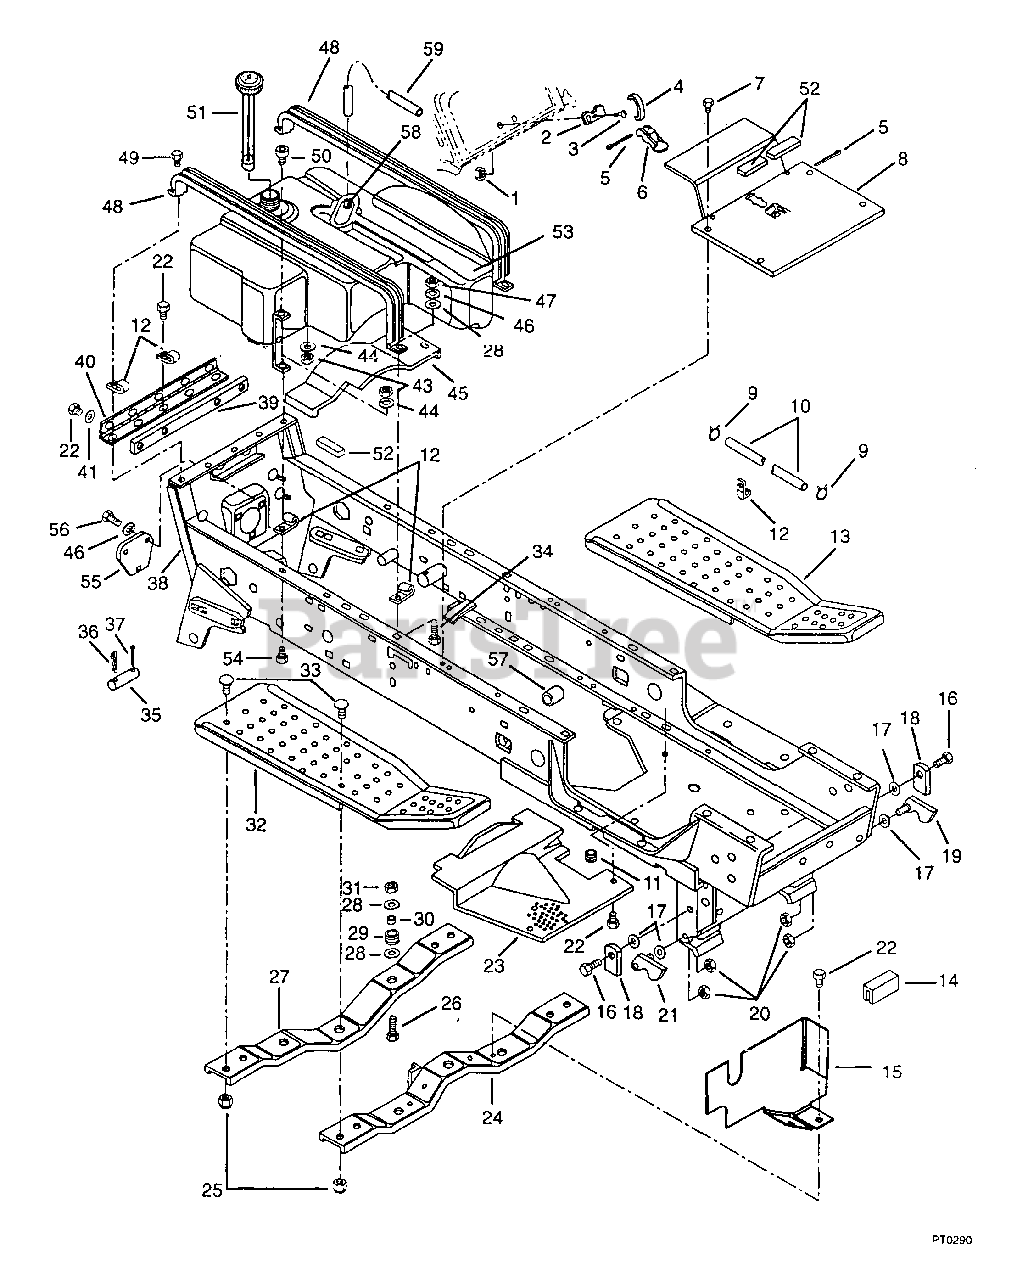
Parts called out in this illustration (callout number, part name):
1	NUT-LK DUAL FACE 10-24 PL
3	SCR-MCH 10-24X.50 SLRH PL
4	SPRING - DECK LATCH
5	PIN-COTR .12 X 1.25 PL
6	LEVER - DECK LATCH
7	SCR-TAP .250-20X.37 HWH PL TR
8	PLATE - FLOOR
9	CLAMP-HOSE WIR.490/.510X.092#8
10	FUEL LINE 1/4 X 67"
11	HOLE PLUG 1.375
12	J-CLAMP
13	L.H. RUNNING BOARD
16	BLT-HEX .38-16X1.00 PL
17	SPRING WASHER
18	LOCK STOP
19	LATCH LH
20	NUT-LK TOP .375-16 GR C YWZC
21	LATCH RH
22	SCR-TAP .312-18X.50 HWH PL TR
24	FRONT CHANNEL
25	NUT-FLG. .312-18 PL
26	BLT-HEX .31-18X1.25 PL GR2
27	REAR CHANNEL
28	WSHR-FL-STL .38X.875X.083 PL
29	GROMMET .438ID X .688 OD
30	SPACER .318X.430X.375
31	NUT-LK .312-18 GR A PL
32	R.H. RUNNING BOARD
33	BLT-RDHDSQSHNK .31-18X.50 YZ
34	BLT-RDHDSQNK .31-18X.75 SHT PL
36	PIN-HAIR INT .14X.4X2.75
37	PIN-COTR .12X1.0 PL
38	MAIN FRAME
40	HINGE-2" X 12.88 YWZC
41	WSHR-FL-STL .38X.875X.083 PL
42	SUPPORT
43	NUT-HEX .250-20 PL
44	WSHR-LK .250X.077 HVY PL
46	WSHR-LK .312X.097 PL HVY
47	NUT-HEX .312-18
48	CHANNEL
49	SCR-TAP .312-18X.75 HWH PL TR
50	SCR-SKH .25-20X.75 TSPH PL
51	GAS GAUGE & CAP
52	FOAM TAPE
53	GAS TANK ASSEMBLY
54	BLT-RDHDSQNK .25-20X.75
56	BLT-HEX .31-18X.75 PL GR2
57	BSHG-SLV .750X.814X .750 BRZ
58	FITTING - GAS TANK
59	GAS TANK FUEL LINE
